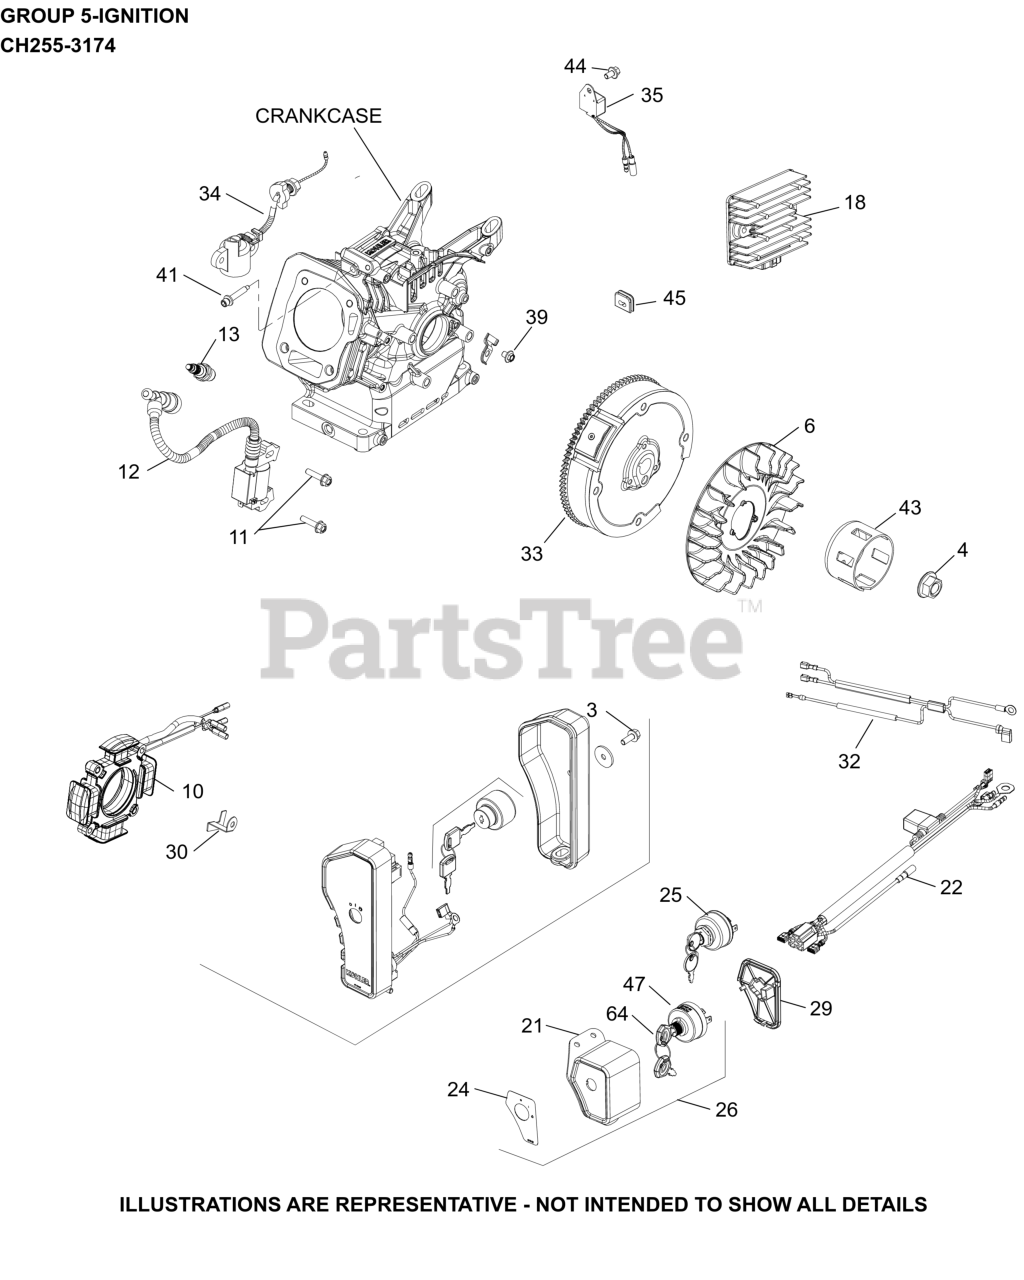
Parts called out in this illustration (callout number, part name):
3	SCREW, HEX FLANGE (M6)-USE 25 086 433-S
4	NUT, FLYWHEEL (W/SERRATIONS)
6	FAN, FLYWHEEL
10	STATOR ASSEMBLY, 3 POLE
11	SCREW, M6 X 25-(#25086436S)
12	MODULE, IGNITION
13	PLUG SPARK 12MM RFI
18	REGULATOR, 10 AMP
21	KIT, KEYBOX HOUSING ASSEMBLY
22	HARNESS, WIRING ASSEMBLY (10 AMP)
24	LABEL, KEY BOX
26	KIT, KEY BOX ASSEMBLY
29	COVER, KEY BOX
30	BRACKET, FIXED STATOR WIRE
32	HARNESS, REGULATOR WIRING ASSY
33	FLYWHEEL ASSEMBLY - 10 AMP
34	SWITCH, OIL SENSOR ASSEMBLY
35	CONTROL, OIL ALERT UNIT
39	SCREW, M6 X 8
41	SCREW, HEX SOCKET HEAD CAP
43	CUP, STARTER
44	SCREW, FLG M6X1.0X10
45	GROMMET, STATOR WIRE
47	SWITCH, KEY ASSEMBLY
64	KIT, KEY PLASTIC HANDLE (2 PC)
